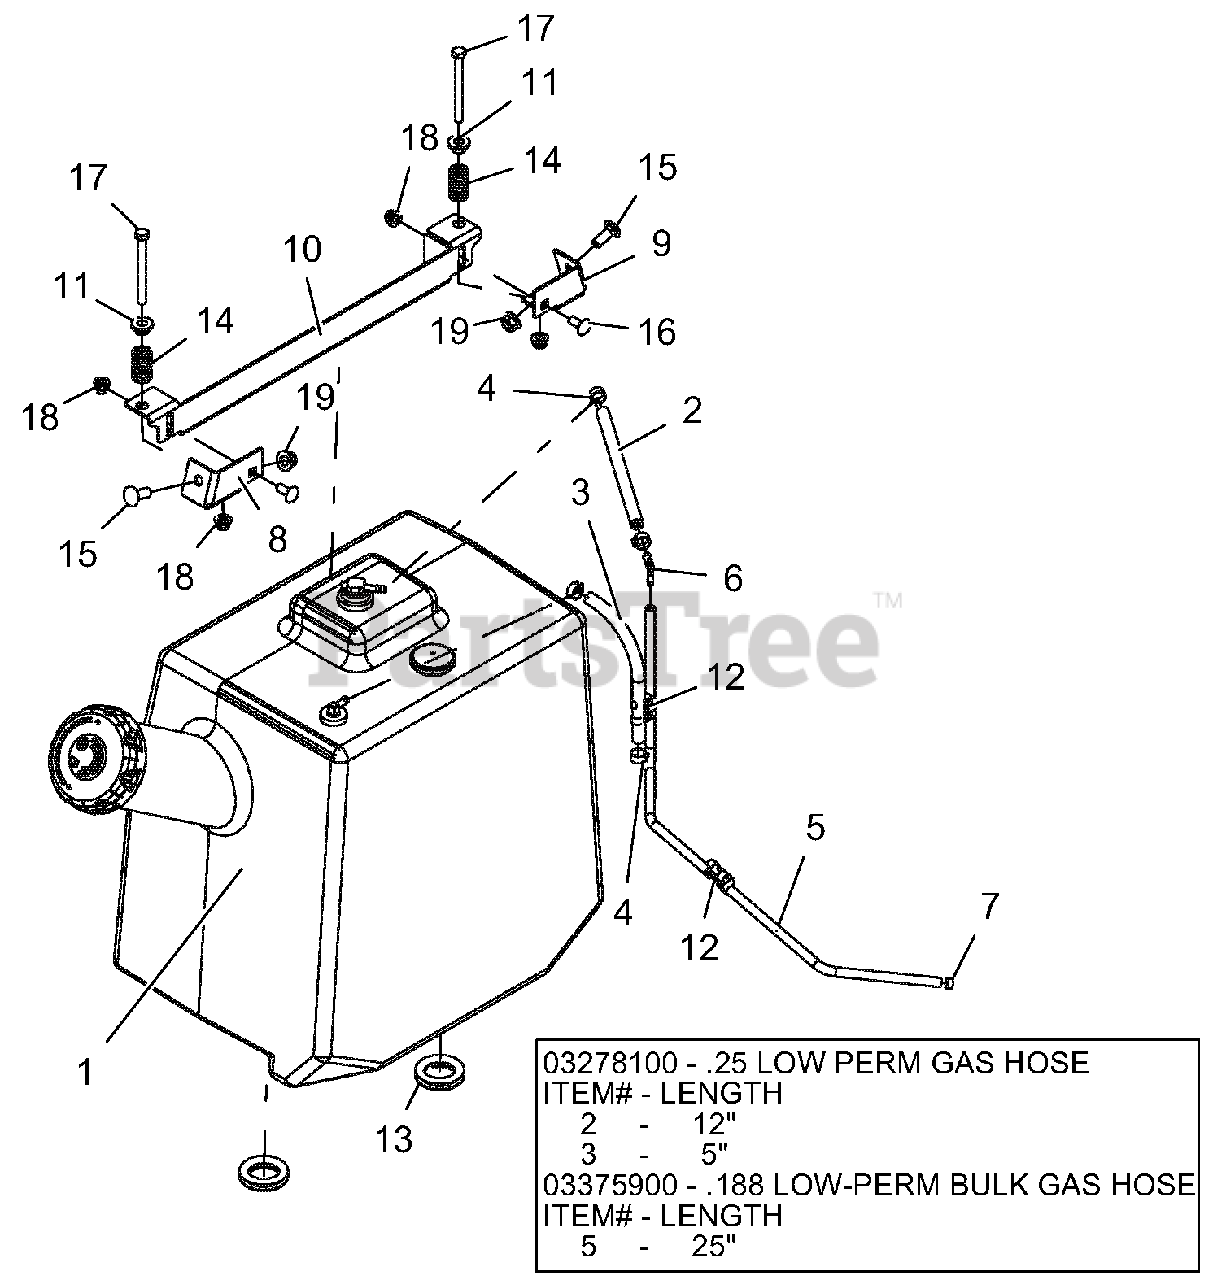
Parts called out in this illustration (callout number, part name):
1	ASSY, EPA PROSTANCE FUEL TANK
2	.25 LOW PERM GAS HOSE
3	.25 LOW PERM GAS HOSE
4	CLAMP, FUEL LINE
5	HOSE, .188 LOW-PERM BULK GAS
6	FITTING-3/16X1/4 90DEGREE VAC
7	CLAMP - HOSE, SPRING .188
8	WLDMT, TANK HOLDDOWN-RH
9	WLDMT, TANK HOLDDOWN-LH
10	HOLDDOWN, FUEL TANK
11	BSHG, FLG .385 X .500 X .875 X .406
12	CLIP, T, .38-.50
13	GROMMET, 1.25"
14	SPRG, COMPRESSION
15	BLT-RDHDSQNK .38-16X1.00 G5 YWZC
16	BLT-RDHDSQNK .31-18X.75 G5 YWZC
17	BLT-HEX .31-18X3.25 GR5 YWZC
18	NUT-LK-NYL-FLG .31-18 YWZC
19	NUT-LK-NYL-FLG .38-16 YWZC
